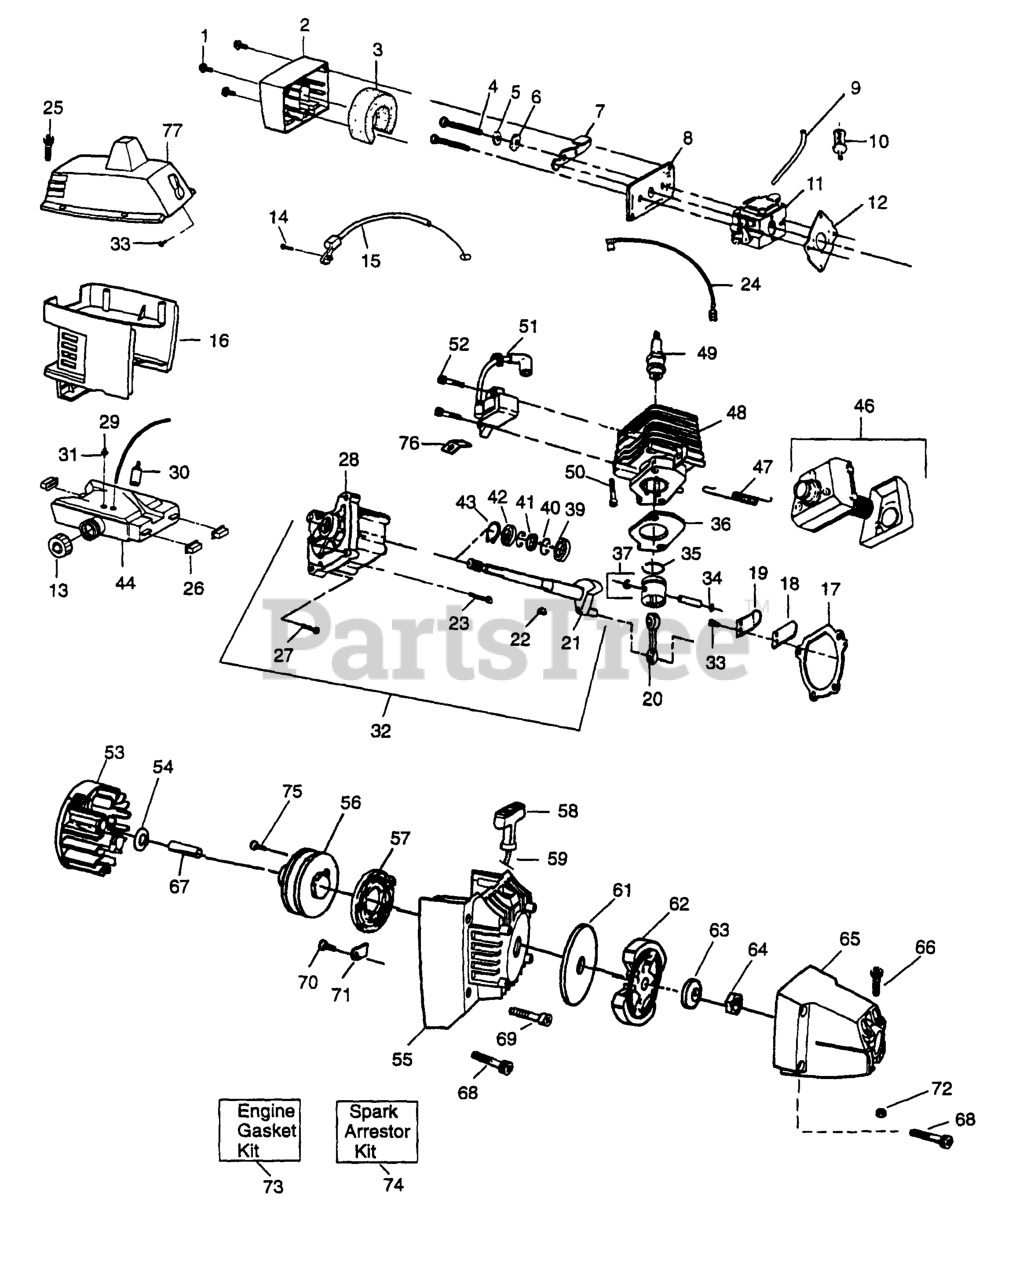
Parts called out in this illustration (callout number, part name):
1	SCREW-10-24 X 13/16
2	COVER
3	AIR FILTER
5	SPACER - CHOKE
7	Choke Shutter
8	Air Filter Plate
9	HOSE. FUEL
10	FUEL PICK UP ASSY
11	CARBURETOR (WA-298A)
12	GASKET-CARB
13	FUEL CAP ASSY.
14	SCREW 8-16 X 9/16 (PLAS
15	THROTTLE CABLE
17	GASKET-C'CASE/SHROUD
18	VALVE-REED
20	ASS'Y-CONNECTING ROD
21	ASSY-CRANKSHAFT
22	KEY-FLYWHEEL
23	SCREW-10-24 X 1" (TAP.)
24	ASSY-WIRE LEAD (BLACK)
25	SCREW-10-14 X 13/16 (PL
27	SCREW 1/4-20 X 7/8 (TAP
28	Crankcase Ass'y.
29	VALVE-CHECK (DUCKBILL)
32	ASSY-C'CASE & C'SHAFT
34	WRIST PIN RET.
35	RING-PISTON (HOOKED)
36	GASKET-CYL W/ADHESIVE
37	KIT-PISTON (32CC)
39	Inner Bearing
40	RING-RETAINING
41	SEAL-CRANKSHAFT
42	BEARING-R8 (OUTER)
43	RING-RETAINING (SHAFT)
44	Fuel Tank Ass'y.
46	KIT-MUFFLER ASS'Y
47	SPRING-MUFFLER
48	CYLINDER
49	Spark Plug
50	SCREW 1/4-20 X 7/8
52	KEY-FLYWHEEL
54	WASHER
55	FAN HSG. ASSY.
56	KIT-STARTER PULLEY
57	SPRING-STARTER
58	STARTER HANDLE 36/41
61	WASHER-CLUTCH
62	KIT-CLUTCH ASS'Y
63	WASHER-BELLEVILLE
65	CLUTCH HSG.
66	SCREW-10-24 X 1-3/8 (UN
67	SPACER-CLUTCH
69	SCREW-10-24X1-3/8-TAPTI
70	SCREW-10-16 X 1/2 HI-LO
72	LOCKNUT-HEX 10-24
73	GASKET KIT
74	Spark Arrestor Kit
76	TAB-45 DEGREE ELECTRICAL
77	COVER-CYLINDER (GRAY)
